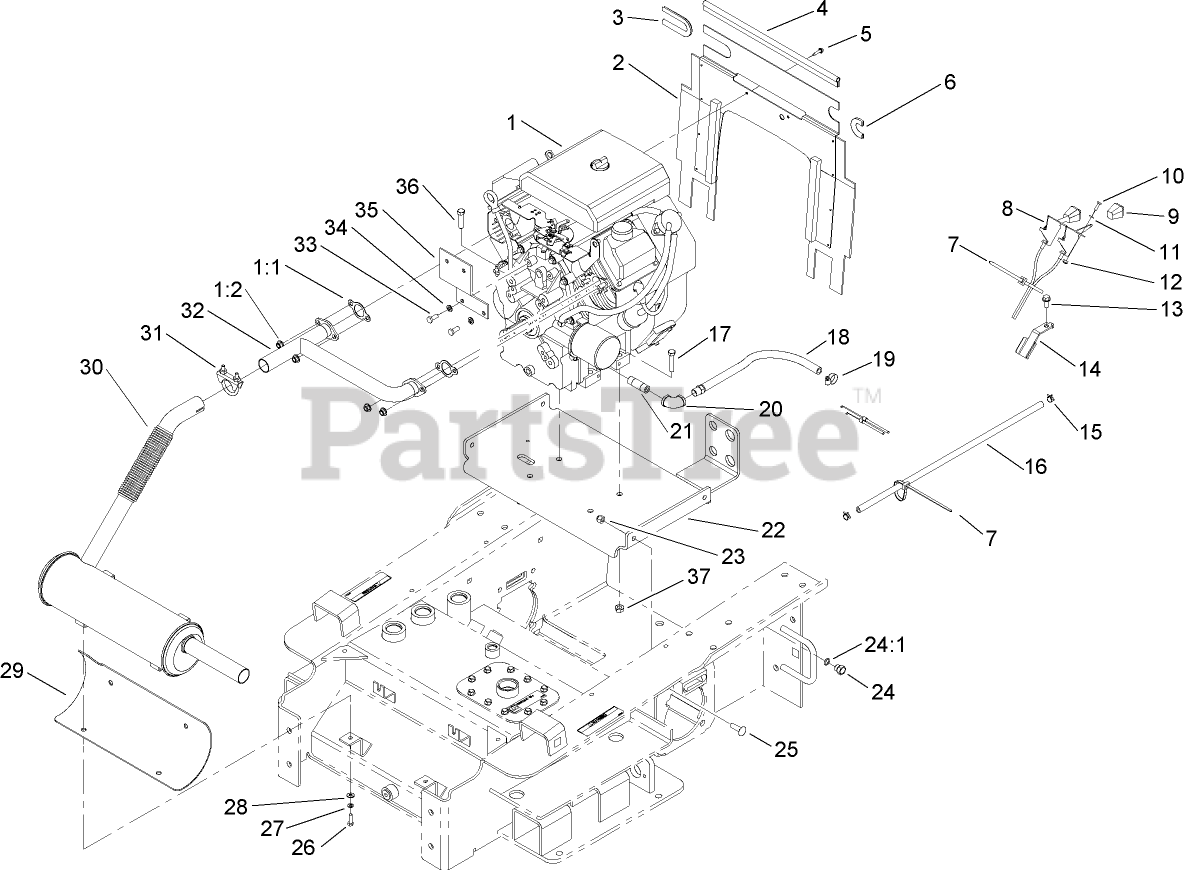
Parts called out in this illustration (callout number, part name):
1:1	GASKET-EXHAUST
1:2	NUT-HF
2	Engine Baffle ASM
3	SEAL-STRIP, 6.5 INCH
4	Seal-Strip, 16 INCH
5	SCREW-SPECIAL
6	SEAL-STRIP, 3 INCH
7	TIE-CABLE
8	CABLE-THROTTLE
11	WASHER-FLAT
12	NUT-LOCK, NI
13	SCREW-HWHTF
14	GUIDE-CABLE
15	CLAMP-HOSE
16	HOSE-FUEL
17	SCREW-HH
18	OIL HOSE ASM
19	CLAMP-HOSE
20	ELBOW-90 DEG
21	NIPPLE
22	ENGINE MOUNTING PLATE ASM
23	NUT-LOCK, NI
24	PLUG-HH
24:1	O-RING
25	SCREW-CARR
26	SCREW-HH
27	WASHER-LOCK
28	WASHER-FLAT
29	SHIELD-HEAT, MUFFLER
30	MUFFLER
31	CLAMP-MUFFLER
32	MANIFOLD-CROSSOVER
33	SCREW-HH
34	WASHER-LOCK
35	BRACKET-SUPPORT, OIL FILTER
36	BOLT-HH
37	NUT-HF
